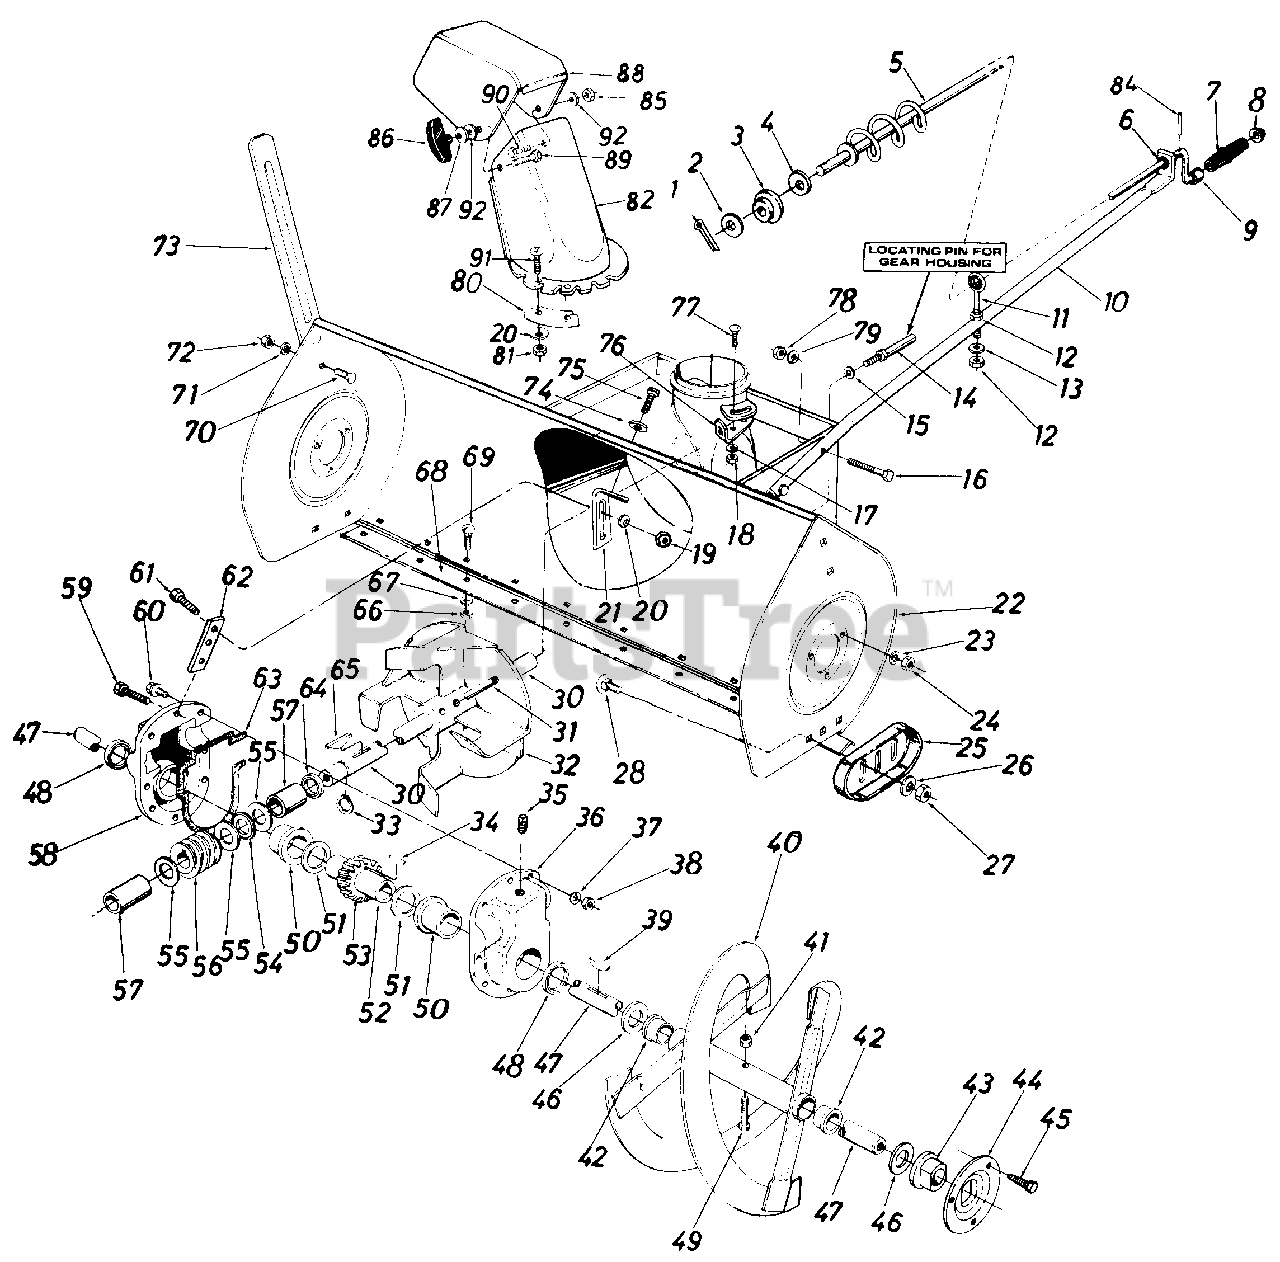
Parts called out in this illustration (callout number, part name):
2	Fl.-Wash. .39" I.D. x .62" O.D.
3	Plastic Bushing
4	Fl.-Wash. .385" I.D. x .62" O.D.
5	Chute Crank Ass'y.
6	Plastic Bushing
7	Knob (Black)
8	Push Nut 3/8" Rod
9	Spacer .385 I.D. x .50" I.D.
10	Chute Crank Support Tubing
12	Hex Nut 5/16-18 Thd.*
13	Bell.-Wash. .345" I.D. x.88" O.D.
14	Stud 3/8-16 x 2.75 " Lg.
15	Bell.-Wash. .400" I.D. x .88" O.D.
16	Hex Bolt 3/8-24 x 1.25" Lg.*
17	Bell.-Wash . . 345 " I.D. x . 88 " O.D.
18	Hex Nut 5/16-18 Thd.*
19	Hex Nut 1/4-28 Thd.
20	Bell.-Wash. .265" I.D. x .75" O.D.
22	45" Snow Blower Housing Ass'y
23	L.-Wash. 5/16" I.D.*
24	Hex Nut 5/16-18 Thd.*
25	Slide Shoe
26	Bell.-Wash. .400" I.D. x .88" O.D.
27	Hex Jam Nut 3/8-16 Thd.
28	Carriage Bolt 3/8-16 x .62" Lg.*
30	Blower Axle .875" Dia. x 14.75" Lg.
31	Spring Pin Spir. 5/16" Dia. x 1.75" Lg.
34	#91 Woodr-Key 1/4 x 3/4" Dia. (HDN)
36	Comp. Gear Hsg. Half-L.H.
37	Spr.-Wash. .32" I.D. x .62" O.D.
38	Hex Ins. L.-Nut 5/16-18 Thd.
39	#91 Woodr-Key 1/4 x 3/4" Dia. (HDN)
41	Hex Ins. L.-Nut 5/16-18 Thd.
42	Plastic Bushing
43	Flange Brg. w/flats 1" I.D.
44	Bearing Housing
45	Hex Sems Bolt 5/16-18 x .75" Lg. *
46	Fl.-Wash. 1.00" I.D. x 1.75" O.D.
48	Flange Bearing 1.503" I.D.
49	Shear Bolt 5/16-18 x 1.75" Lg.
50	Oil Seal 1.50" I.D.
51	Fl.-Wash.1.50" I.D. x 2.00" O.D
52	Worm Gear Shaft
53	Double Threaded Worm Gear- 0 L.H.
54	Thrust Brg.-.88" I.D. x 1.44" O.D.
55	Fl.-Wash. .88 " I.D. x l.4 " O.D.
56	Double Threaded Worm-L.H.
57	Sleeve
58	Complete Gear Hsg. Half-R.H.
59	Hex BoIt 5/16-18 x l.25" Lg.*
60	Hex Bolt 5/16-18 x 1.0" Lg. (Grade 5)
61	Hex Bolt 1/4-28 x .75" Lg.
62	Gear Housing Support Plate
63	Rubber Gasket
64	Oil Seal-.875" I.D.
65	#9 Hi-Pro Key 3/16 x 3/4" Dia. (HT.)
66	Hex Nut 5/16-18 Thd.*
67	L.-Wash.5/16" I.D.*
69	Carriage Bolt 5/16-18 x 1.00" Lg. *
70	Carriage Bolt 5/16-18 x .62"-Lg.*
71	L.-Wash . 5/16" I.D.*
72	Hex Nut 5/16-18 Thd.*
73	Guide Blade
74	Bell.-Wash. .345" I.D. x .88" O.D.
75	Hex Wash. Hd. AB Tap Scr 5/16 x .75 " Lg.
77	Carriage Bolt 5/16-18 x .75" Lg.*
78	Hex Ins. L.-N ut 3/8-24 Thd.
79	L.-Wash. 3/8" I.D.*
80	Chute Flange Keeper
81	Hex Nut 1/4-20 Thd. *
82	Chute Ass'y. w/Chute Guard
84	Bell.-Wash. .345" I.D. x .88" O.D.
85	Hex Cent. L.-Nut 5/16-18 Thd.
86	Knob Handle
87	Bell.-Wash. .345" I.D. x .88" O.D.
88	Top Chute Ass'y.
89	Carriage Bolt 5/16-18 x 1.00" Lg.*
90	Carriage Bolt 5/16-18 x .62" Lg.*
91	Truss Mach. Scr. 1/4-20 x .75"
92	Roll Pin .12 Dia. x .63"
